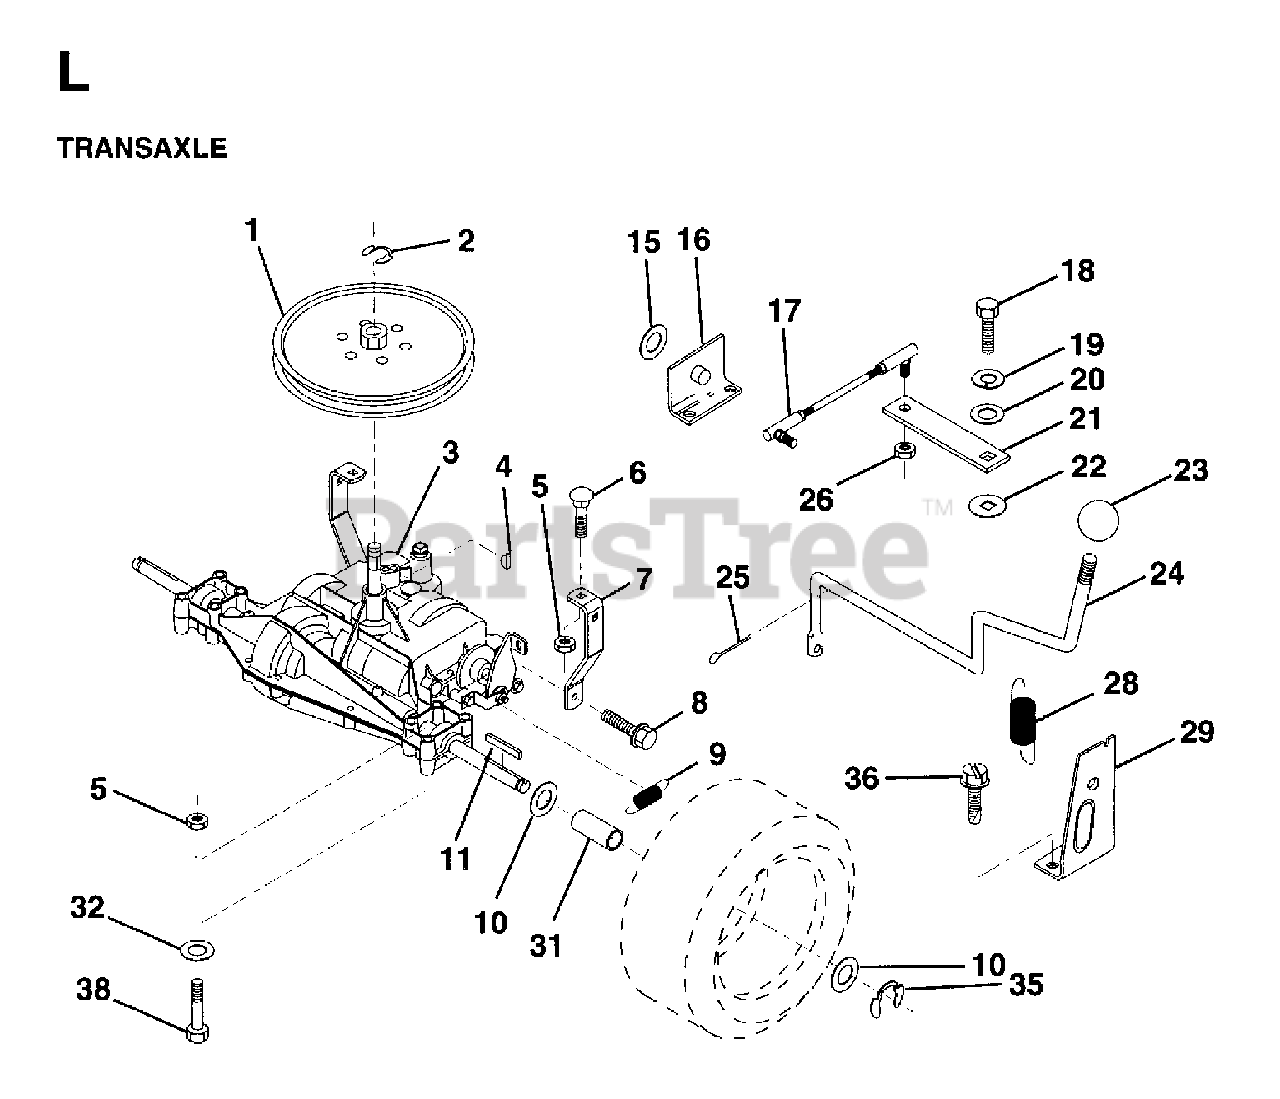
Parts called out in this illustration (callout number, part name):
2	RETAINING RING LT
5	LOCKNUT
6	BOLT
7	STRAP,TORQUE
8	SCREW
9	SPRING,BRAKE RETURN
11	SQUARE KEY
15	WASHER
16	SUPT, HDLE SHT LH
18	BOLT 1/4-28X3/4
19	LOCKWASHER
20	WASHER LT
22	WASH-SHFT PLT LT
23	KNOB.DUCKHEAD.1/2
24	ROD, SHIFT
25	PIN COTTER
26	LOCKNUT
28	SPRING.EXTENSION
29	SUPPORT HANDLE SHAFT RH
31	SPACER AXLE
32	WASHER
35	E-RING LT
36	SCREW
38	BOLT HEX 5/16-18 GR 5
